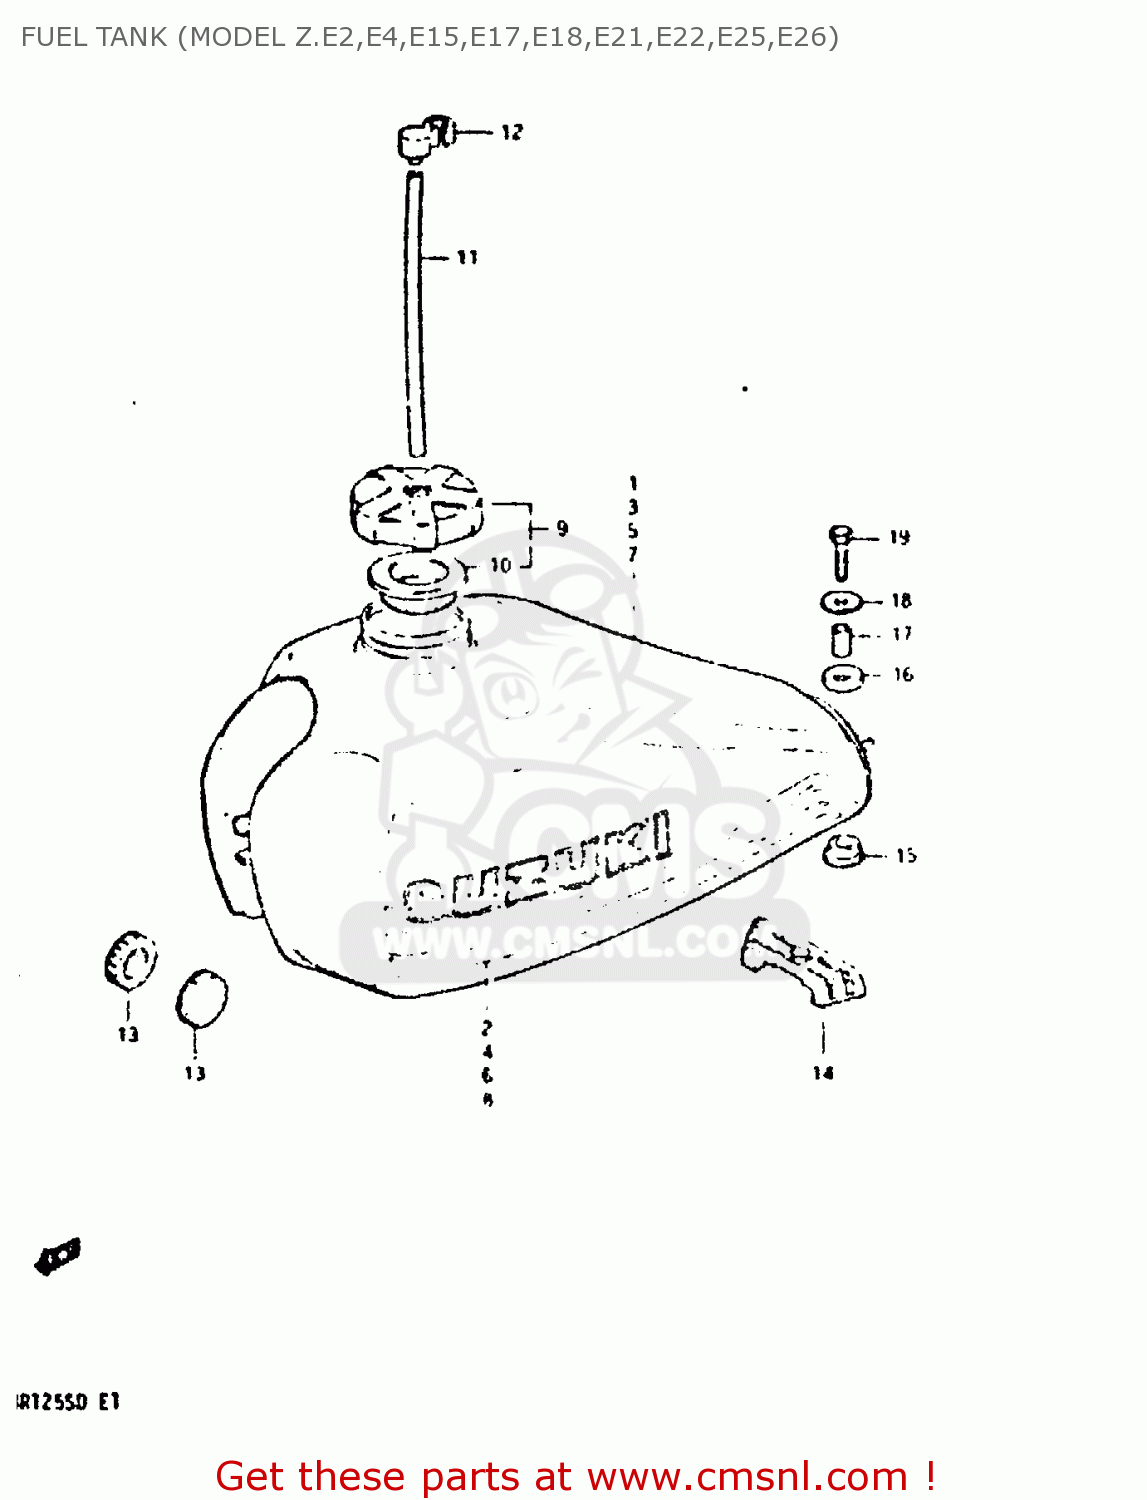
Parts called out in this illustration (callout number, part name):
1	TANK, FUEL (BLACK)
2	TAPE SET
3	TANK FUEL (BLUE)
4	TAPE SET
5	TANK, FUEL (YELLOW)
6	TAPE SET,FUEL TANK
7	TANK, FUEL (RED)
8	TAPE SET
9	CAP SET,FUEL TANK
10	GASKET (NAS)
11	HOSE
12	CLAMP,FUEL TANK BREATHER HOSE
13	CUSHION
14	CUSHION,FUEL TANK,REAR
15	CUSHION
16	CUSHION
17	SPACER(8.5X12X19)
18	WASHER (8.5X29X1.6)
19	BOLT (8X30)
